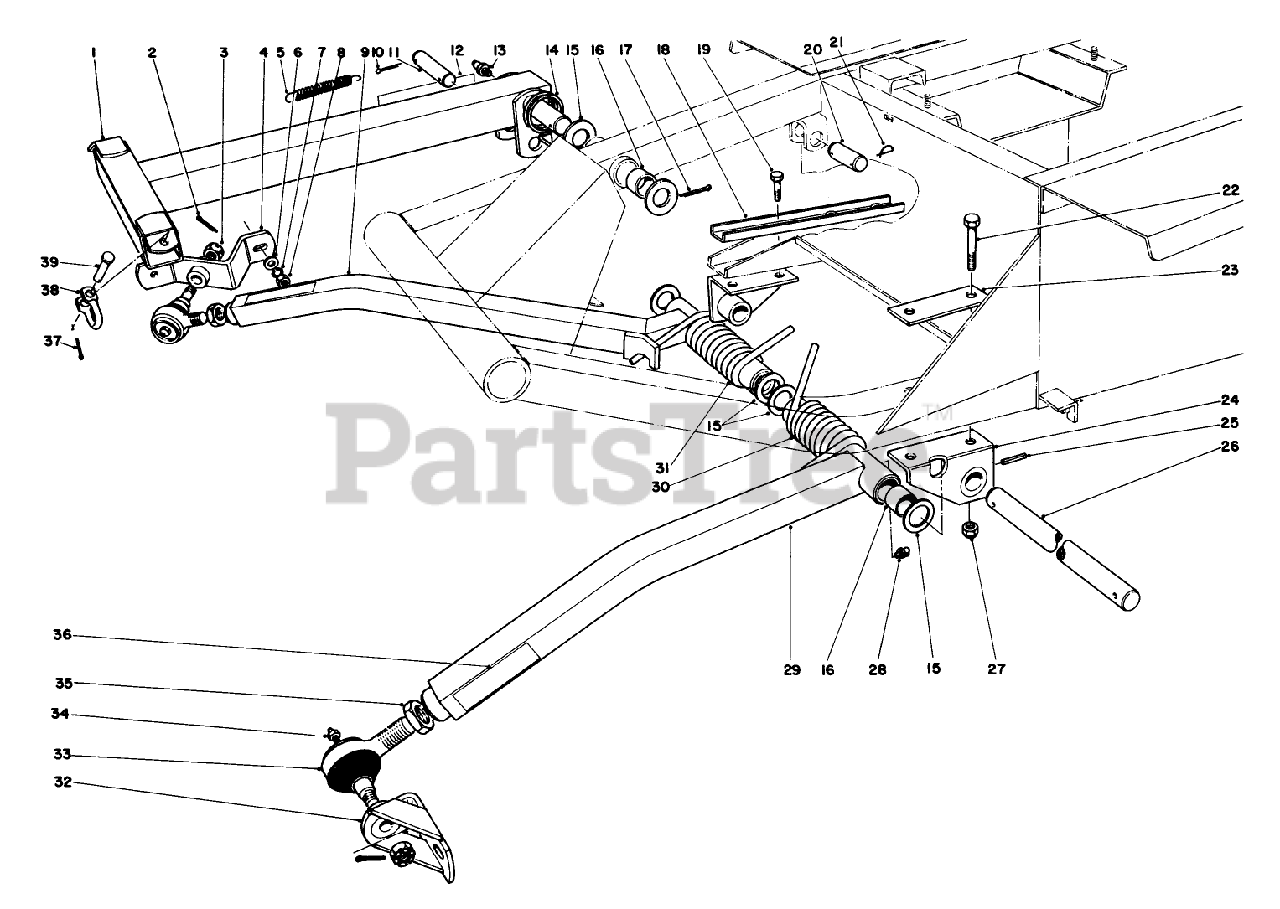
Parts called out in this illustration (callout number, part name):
1	Lift Arm
2	PIN-COTTER
3	NUT-SHH
4	Ball Joint Mount
5	SPRING-EXTENSION
6	WASHER-FLAT
7	WASHER-LOCK
8	NUT-HEX
9	Push Arm R.H. (Incl. Ref. #16 & 28)
10	PIN-COTTER
12	Decal-Warning
13	FITTING-GREASE
14	Spring Lift Arm
15	WASHER-FLAT
16	BUSHING
17	PIN-COTTER
18	Support Reinforcement
19	SCREW-HH
20	PIN-CLEVIS
21	PIN-LYNCH
22	SCREW-HH
23	SUPPORT PLT
24	Bracket-Push Arm
25	PIN-SPIRAL
26	SHAFT-PIVOT
27	NUT-LOCK, NI
28	FITTING-GREASE
29	Push Arm L.H. (Incl. Ref. #16 & 28)
30	Spring-Torsion LH
31	Spring-Torsion RH
32	LH BALL JOINT MT WA
33	Ball Joint
34	FITTING-GREASE
35	NUT-HJ
36	Decal Warning
37	PIN-COTTER
38	SHACKLE
39	PIN-CLEVIS
